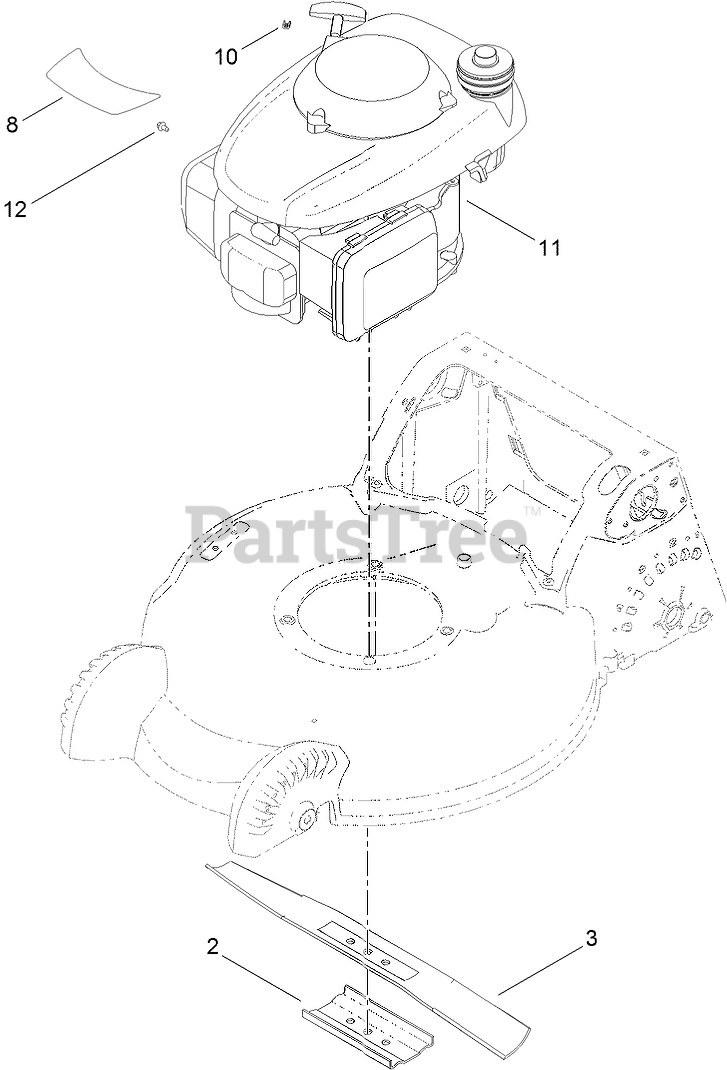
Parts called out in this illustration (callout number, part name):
2	SUPPORT-BLADE
3	BLADE-21 INCH
8	DECAL-ENGINE
10	STOP-ROPE
12	SCREW-HWH
